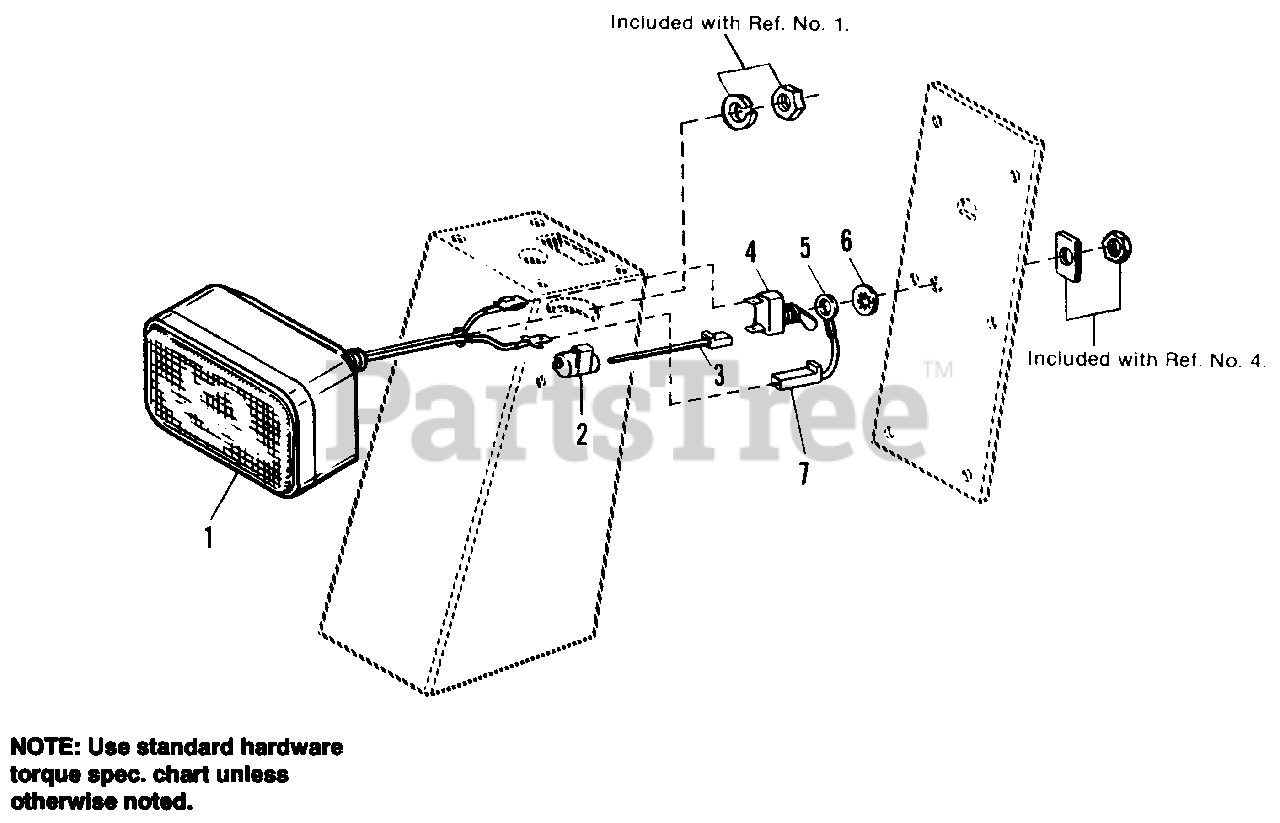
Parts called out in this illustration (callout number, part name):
1	HEADLIGHT ASSY.
2	CONNECTOR, Wire, Self-Stripping
3	WIRE ASSY.
4	SWITCH, Toggle
5	WIRE ASSY. (Ground)
6	LOCKWASHER, Int. Tooth, 1/2" I.D.
7	CONNECTOR BODY
